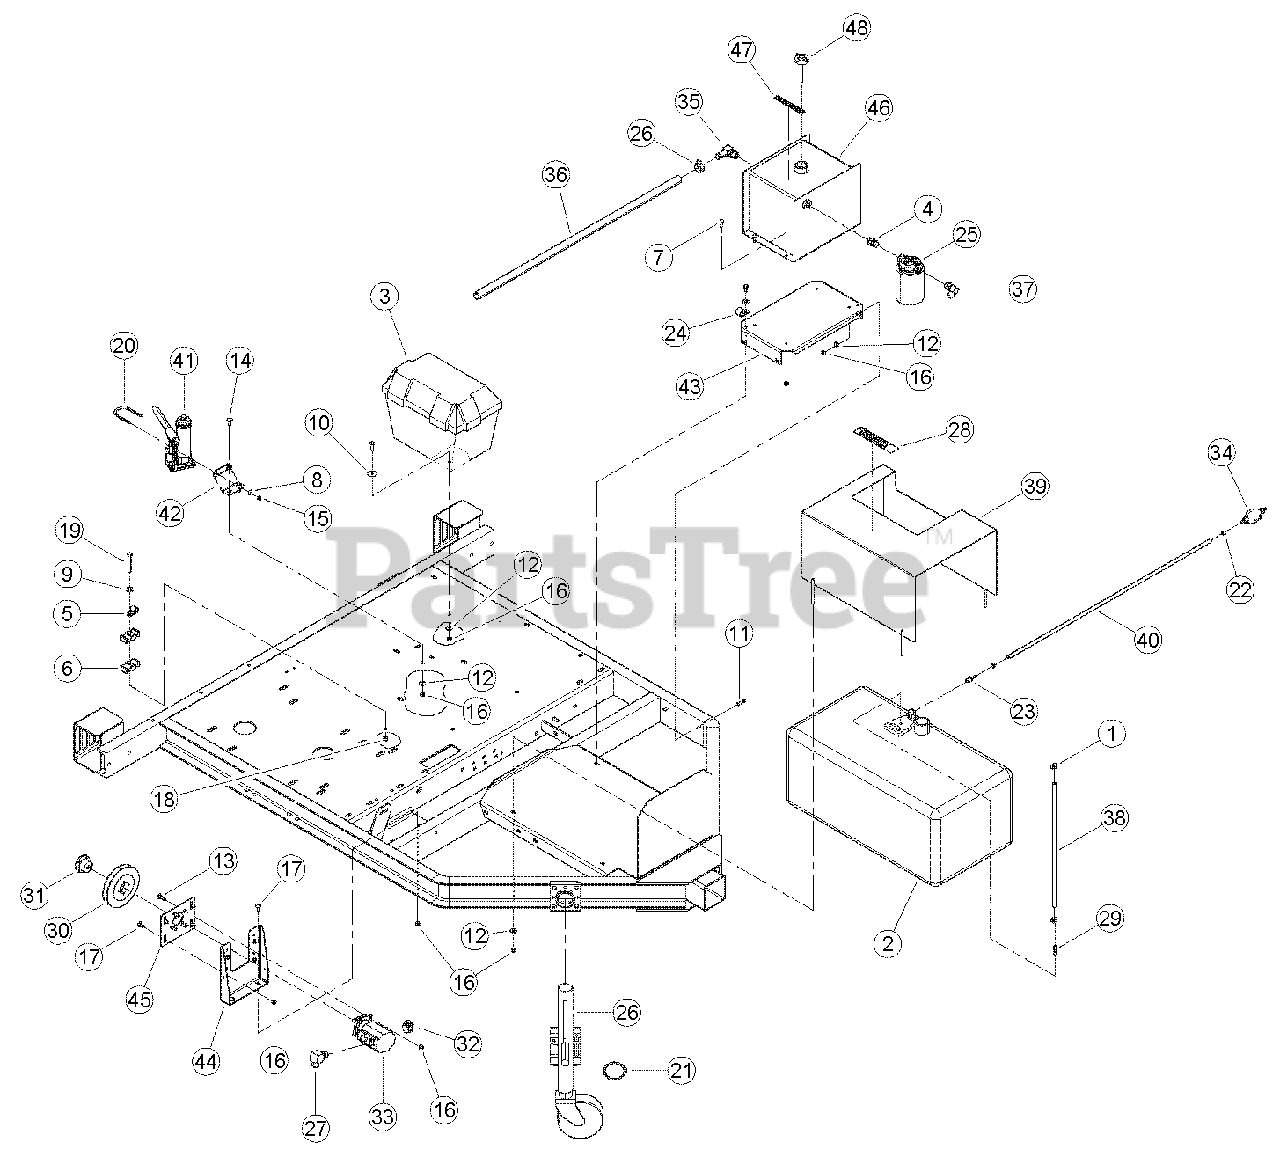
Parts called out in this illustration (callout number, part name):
1	CLAMP, HOSE 5/16 X 5/8 DIA. MAX.
2	TANK, 19 GAL FUEL
3	BOX, PLASTIC BATTERY
4	ADAPTER, -8 MORING / -8 MJIC
5	CLAMP, 9/16 COATED
6	CLAMP, PLASTIC OSE
7	BOLT, 5/16 X 3/4 HEX HD GR5 ZP
8	WASHER, 1/4 FLAT ZP
9	WASHER, 3/8 FLAT ZP
10	WASHER, 5/16 FENDER ZP
11	BOLT, 5/16 X 1 HHCS GR5 NC ZP
12	WASHER, 5/16 FLAT ZP
13	BOLT, 5/16 X 1 CRG GR5 ZP
14	BOLT, 5/16 X 7/98CRG GR5 NC ZP
15	NUT, 1/4 NE NYLOCK ZP
16	NUT, 5/16 NE NYLOCK ZP
17	BOLT, 5/16 X 3/4 CRG GR5 NC ZP
18	NUT, 3/8 NE NYLOCK ZP
19	BOLT, 3/8 X 2-3/4 HHCS GR5 NC ZP
20	U-BOLT, 1/4 X 1-1/2 PIPE
21	SNAP RING, 2-1/2 EXTERNAL
22	CLAMP, 15/32 SPRING
23	FITTING, 1/4 NPT. X 1/4 HOSE
24	CLAMP, 1 IN. COATED METAL
25	FILTER, SPIN-ON
26	JACK, PIVOTING W/SWIVEL CASTOR
27	ADAPTER, -10 MORING / -10 MJIC 90 DEG.
28	DECAL, DIESEL FUEL
29	FITTING, 1/8 MNPT X 1/4 HOSE
32	CLAMP, 1-5/32 TO 7/32 OD RANGE T-BOLT
33	PUMP, 2 STAGE CW HI/LO 0.605 DISP.
34	PUMP, HAND PRIMER
35	ADAPTER, -10 MORING / .75 90 DEG. HOSE
36	HOSE, .75 ID. X 38 IN. 100R4 HYD.
37	ADAPTER, -8 MORING / -8 MJIC 90 DEG.
38	HOSE, 76 IN. FUEL RETURN
39	WELDMENT, FUEL TANK CLAMP
40	HOSE, 38 IN. FUEL LINE
41	JACK, HYDRAULIC 2 TON
42	PLATE, JACK MOUNT
43	SHEET, TANK MOUNT
44	BRACKET, MOUNT HYDRAULIC PUMP
45	PLATE, MOUNT HYDRAULIC PUMP (WAS 75966-12, REPLACED AND SUPERSEDED. FOR SERVICE ORDER PN 77090-12, PLATE, PUMP MOUNT)
46	ASSEMBLY, HYD. TANK 3.25 GAL, SERVICE PART
47	DECAL, HYDRAULIC FLUID
48	CAP, W/DIPSTICK
48	PLATE, PUMP MOUNT
